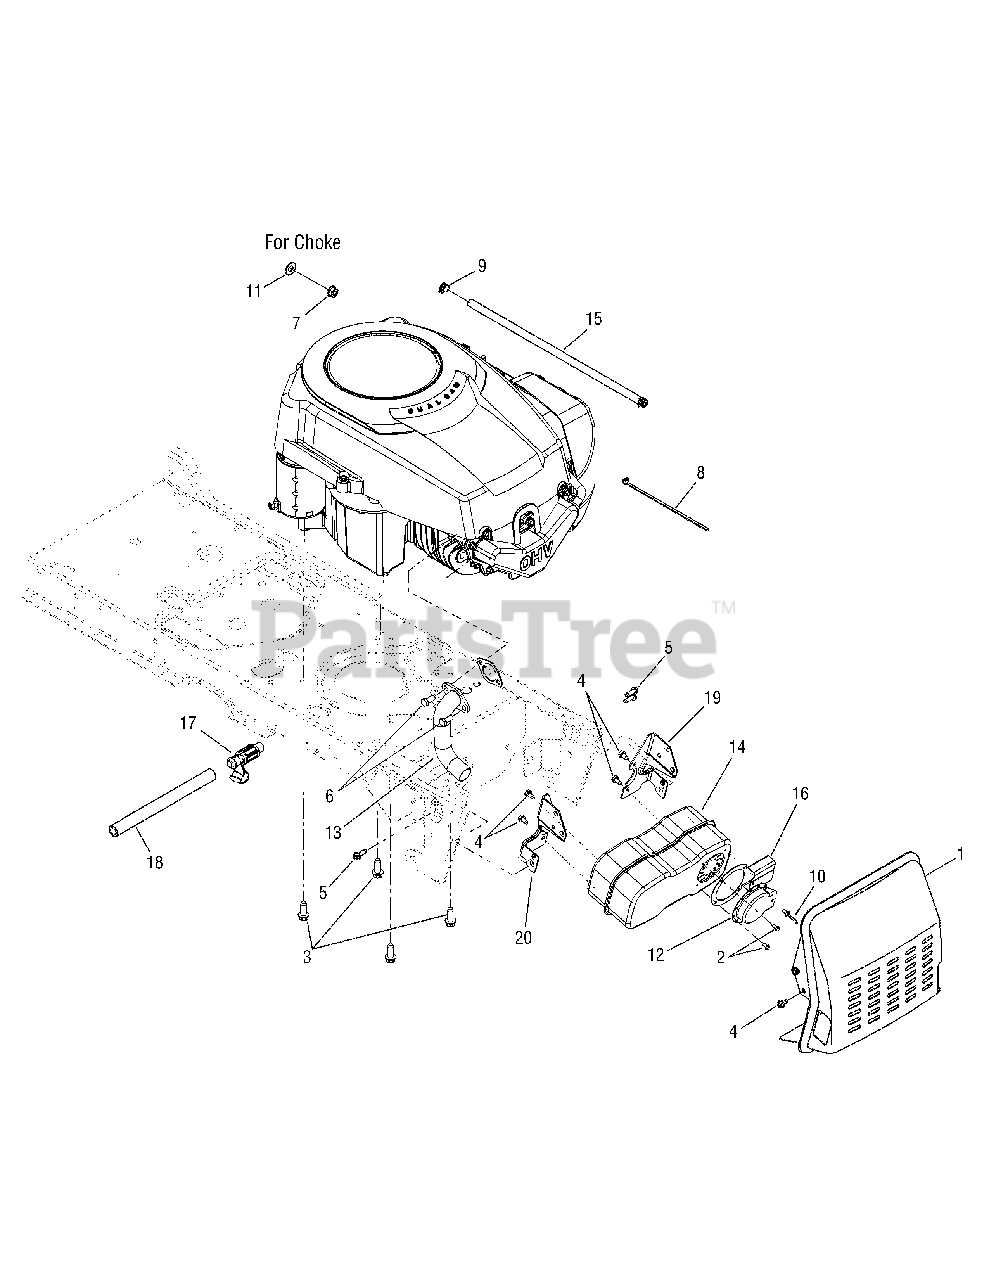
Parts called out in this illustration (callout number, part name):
2	Screw, Hex Wash Hd. Tapp, #8-18 x .5
3	Screw, Hex Sems Tapp, 3/8-16 x 1.0
4	Screw, Hex Wash Hd. Tapp, 1/4-20 x .5
5	Screw, Hex Wash Hd. Tapp, 1/4-20 x .75
6	Screw, Hex Cap, 5/16-18 x .75 Gr5
7	Nut, Hex Flange Lock, 3/8-16 Gr5
8	Tie, Cable
9	Clamp, Hose
10	Rivet, Pop, .188 x .3
11	Washer, Flat, .406 x .875 x .059
12	Deflector, Muffler
13	Pipe Exhaust
14	Muffler, Single Inlet
15	Hose, Fuel ; Low Permeation, 51 inches
16	Deflector, Muffler
17	Valve, Oil Drain
18	Hose, Oil Drain Extension
